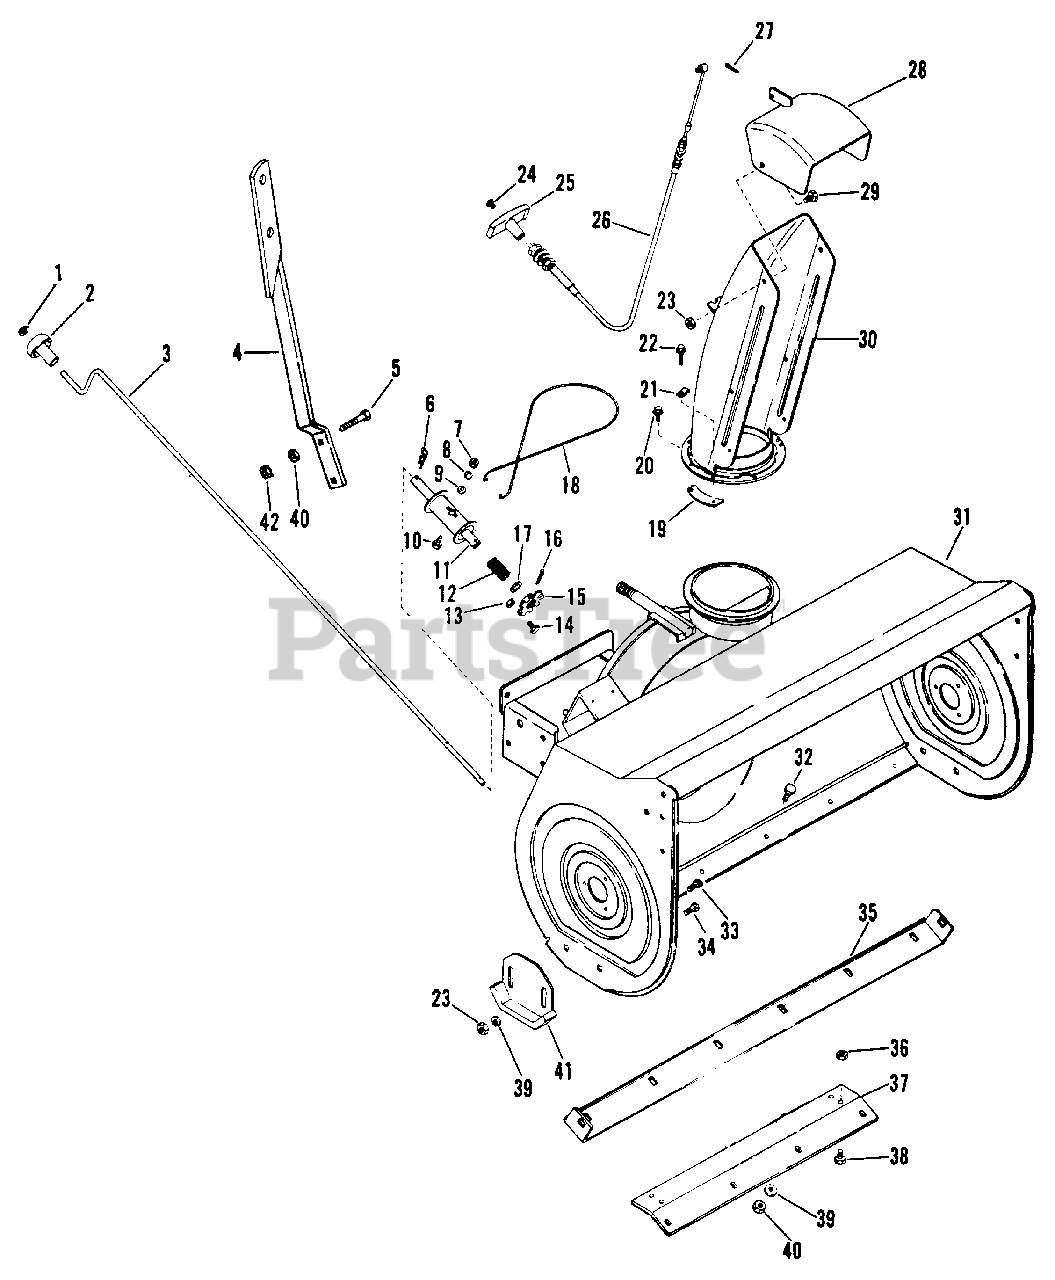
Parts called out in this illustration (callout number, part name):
1	Nut, Lock 3/8-16
2	Knob
3	Chute Control Crank
4	Chute Crank Support
5	Tap Bolt 5/16-18x1-1/2
6	Hair Pin 3/32x1-27/64
7	Nut, Hex 1/4-20
8	Lock Washer 5/16 I.D.
9	Washer, Flat .263x.562x.040
10	Bolt, 1/4-20x.625 Rd Hd Sq Nk
11	Spool
12	Compression Spring 1.6
13	Twin Whiz-Lock Nut 10-24
14	Cap Screw 10-24x3/8
15	Disc Assembly
16	Pin, Spring .187x1.000
17	Washer .638/.645x1.005x.062
18	Cable
19	Chute Clamp
20	Screw, Tapping 10-24x.50 HHD
21	Cable Clamp
22	Taptite 10-24x31/64
23	Nut, Lock 3/8-16
24	Screw, Machine 8-32x.75 PHD
25	Black Knob
26	Control Cable
27	Pin, Cotter 3/32x.75
28	Chute Deflector
29	Bolt, Hex 3/8-16x.75
30	Discharge Chute
31	40" Auger/Impeller Housing
32	Bolt, Carriage 5/16-18x.75
33	Bolt, Carriage 3/8-16x.75
34	Bolt, 3/8-16x1.00 Rd Hd Sq Nk
35	Scraper Blade
36	Nut, Lock 3/8-16
37	Scraper Blade Brace
38	Bolt, Hex 3/8-16x.75
39	Washer, Flat .406x.812x.065
40	Two Way Lock Nut 5/16-18 Gr A
41	Skid
42	Nut, Lock 5/16-18
